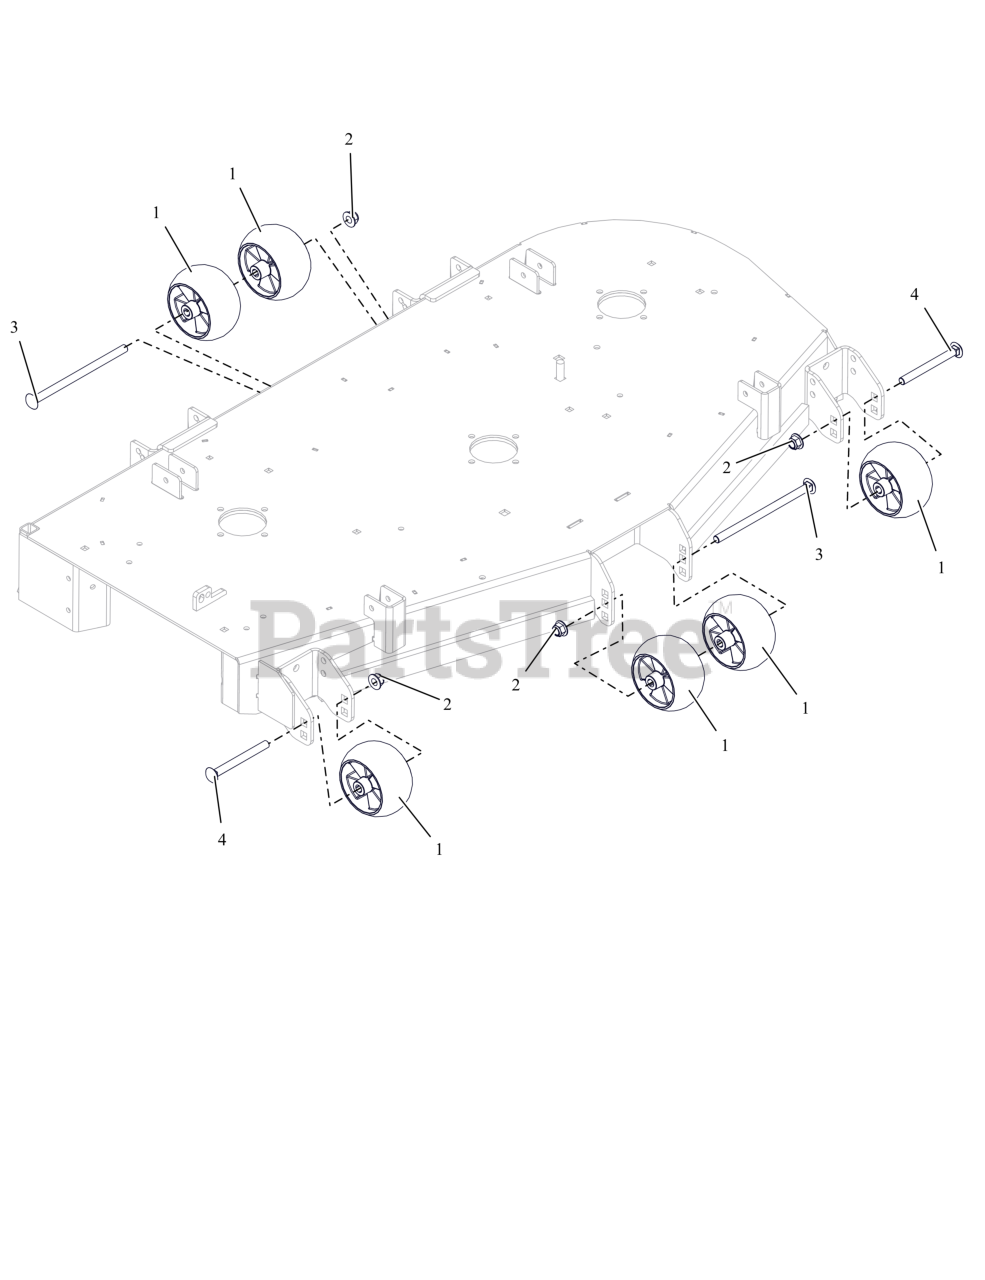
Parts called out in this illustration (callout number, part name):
1	WHEEL, ANTI SCALP - 5X3 CTR W/RIBS
2	NUT,NYL-FLG .50-13 GF ZCC
3	BTL,RHSN .500-13 X 8.5S G5 ZCC
4	BLT, RHSN .50-13X5.00 G5 ZCC
